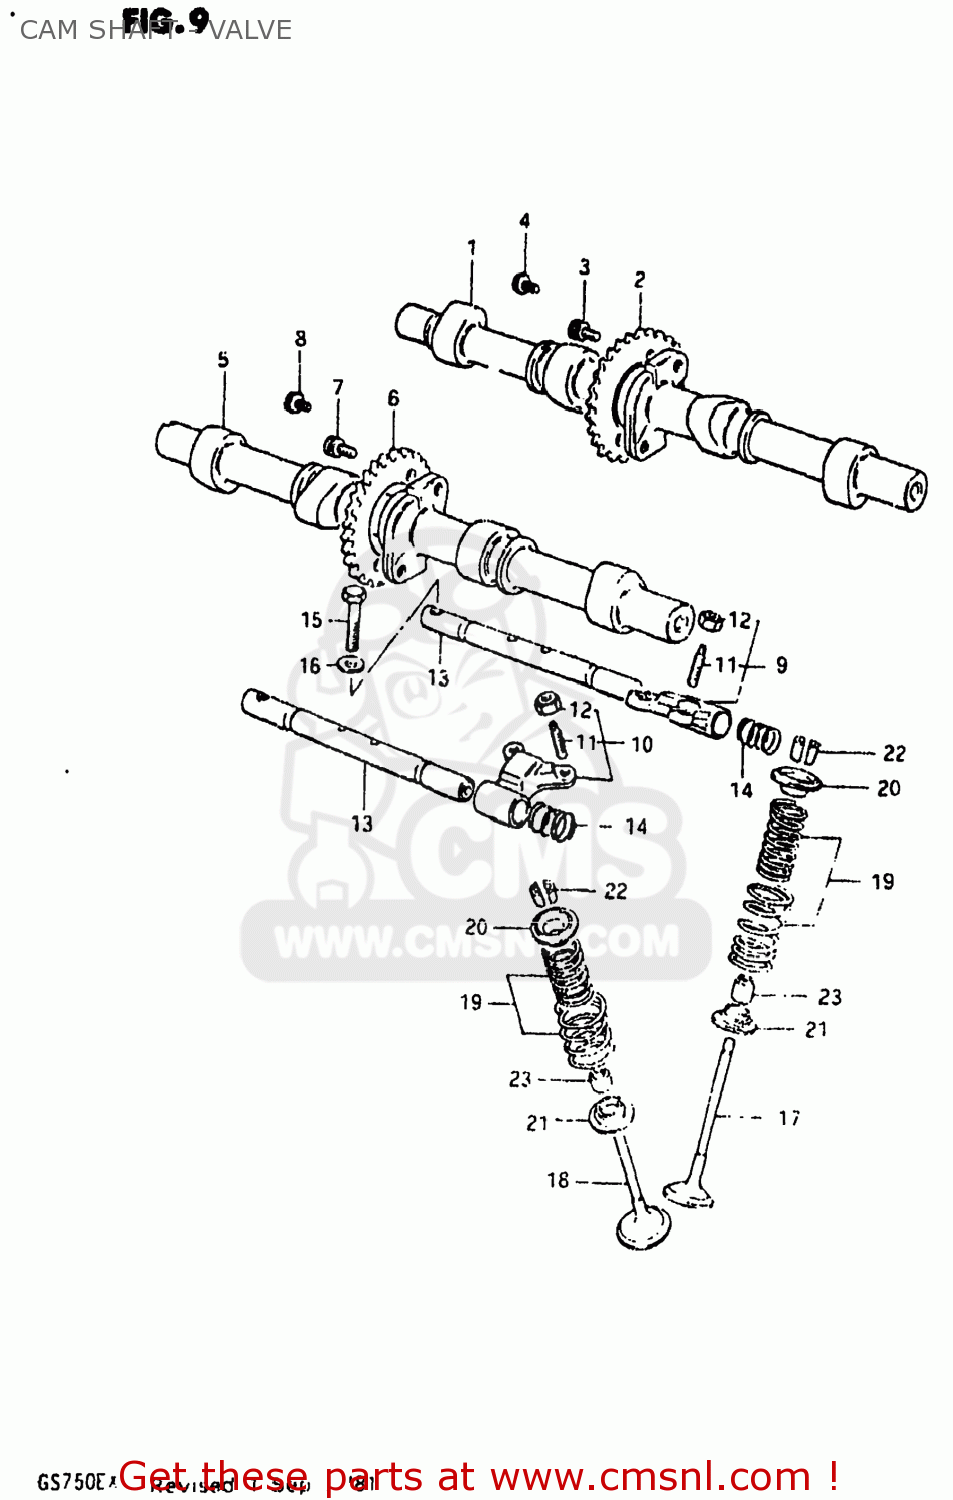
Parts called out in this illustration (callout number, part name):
1	CAMSHAFT
2	SPROCKET,CAMSHAFT
3	BOLT 6X11
4	BOLT(7X11)
5	CAMSHAFT,EXHAUST
6	SPROCKET,EXHAUST CAMSHAFT
7	BOLT 6X11
8	BOLT(7X11)
9	ARM,VALVE ROCKER
10	ARM,VALVE ROCKER
11	SCREW,TAPPET ADJUSTING
12	NUT,ADJUSTING
13	SHAFT,VALVE ROCKER
14	SPRING
15	BOLT
16	WASHER
17	VALVE,INTAKE
18	VALVE,EXHAUST
19	SHIM,TAPPET
20	RETAINER,VALVE SPRING
21	SEAT,VALVE SPRING
22	COTTER VALVE
23	OIL SEAL
